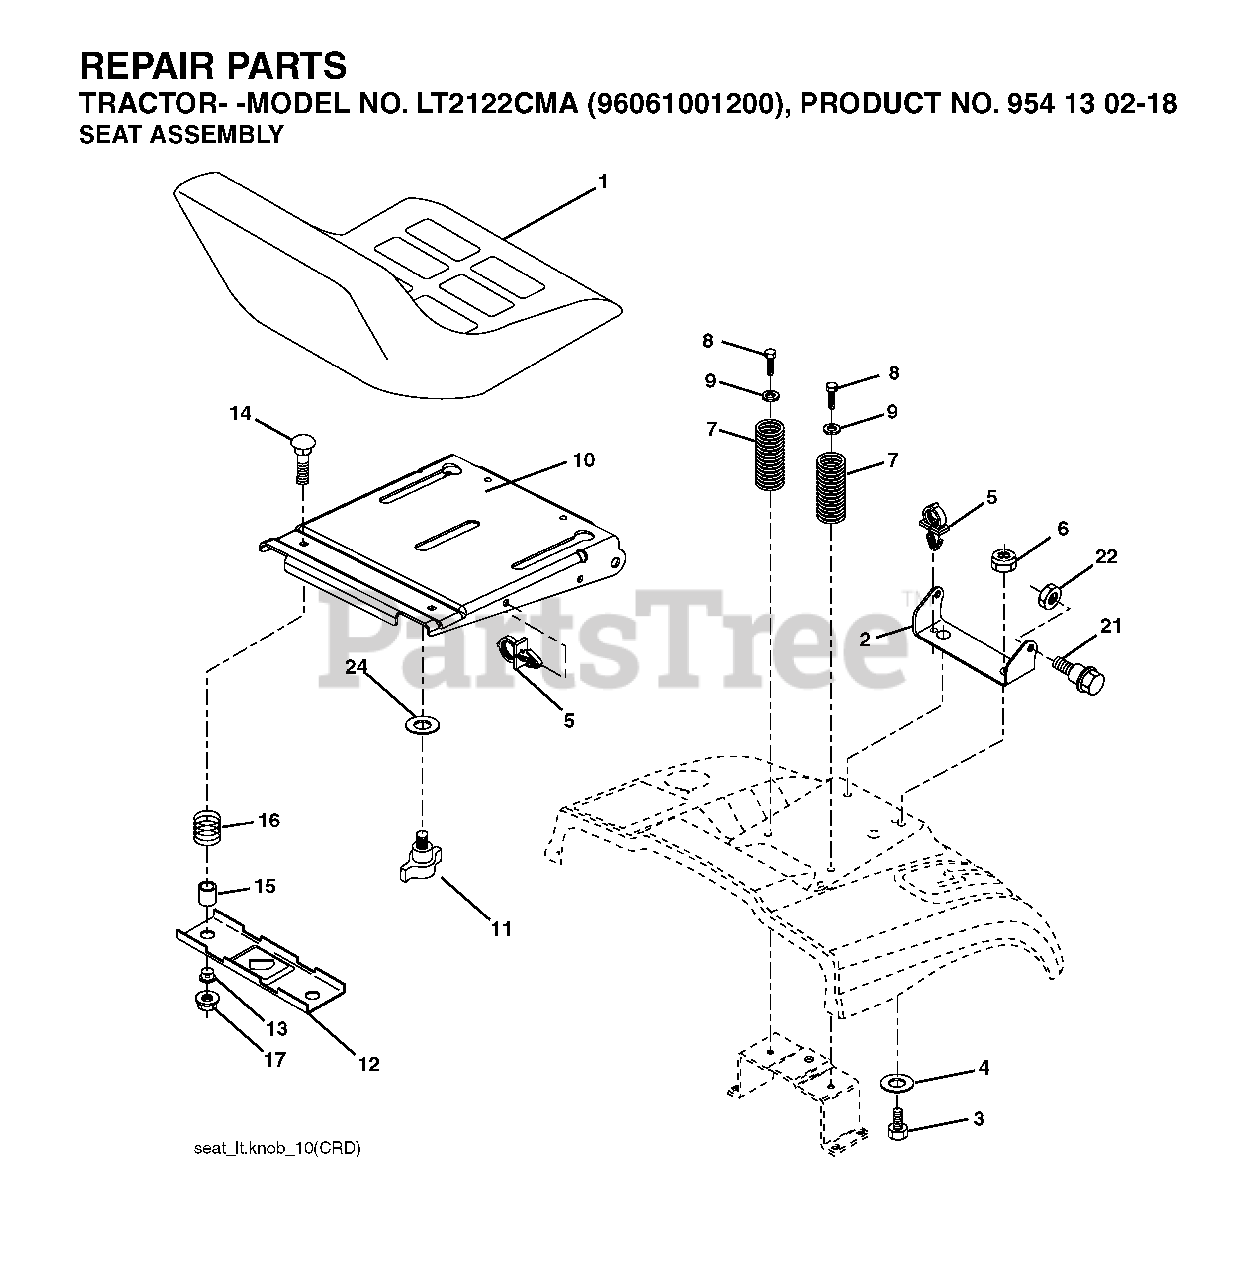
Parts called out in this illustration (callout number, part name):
2	BRKT.PIVOT.FENDER
4	WASHER PM
5	PUSH CLIP
6	NUT
7	SPRING COMPRESSION
8	SCREW 3/8-16X1
9	WASHER
11	KNOB.SEAT.ADJ.WINGNUT
12	BRKT SWITCH
14	BOLT.ROUND.HEAD.SQUARE.NECK
15	SPACER SPLIT
16	SPRING COMPRESSED
17	NUT T
21	BOLT.SHOULDER.5/16-18
22	NUT.71038.31-18.HEX.NYLOCK
